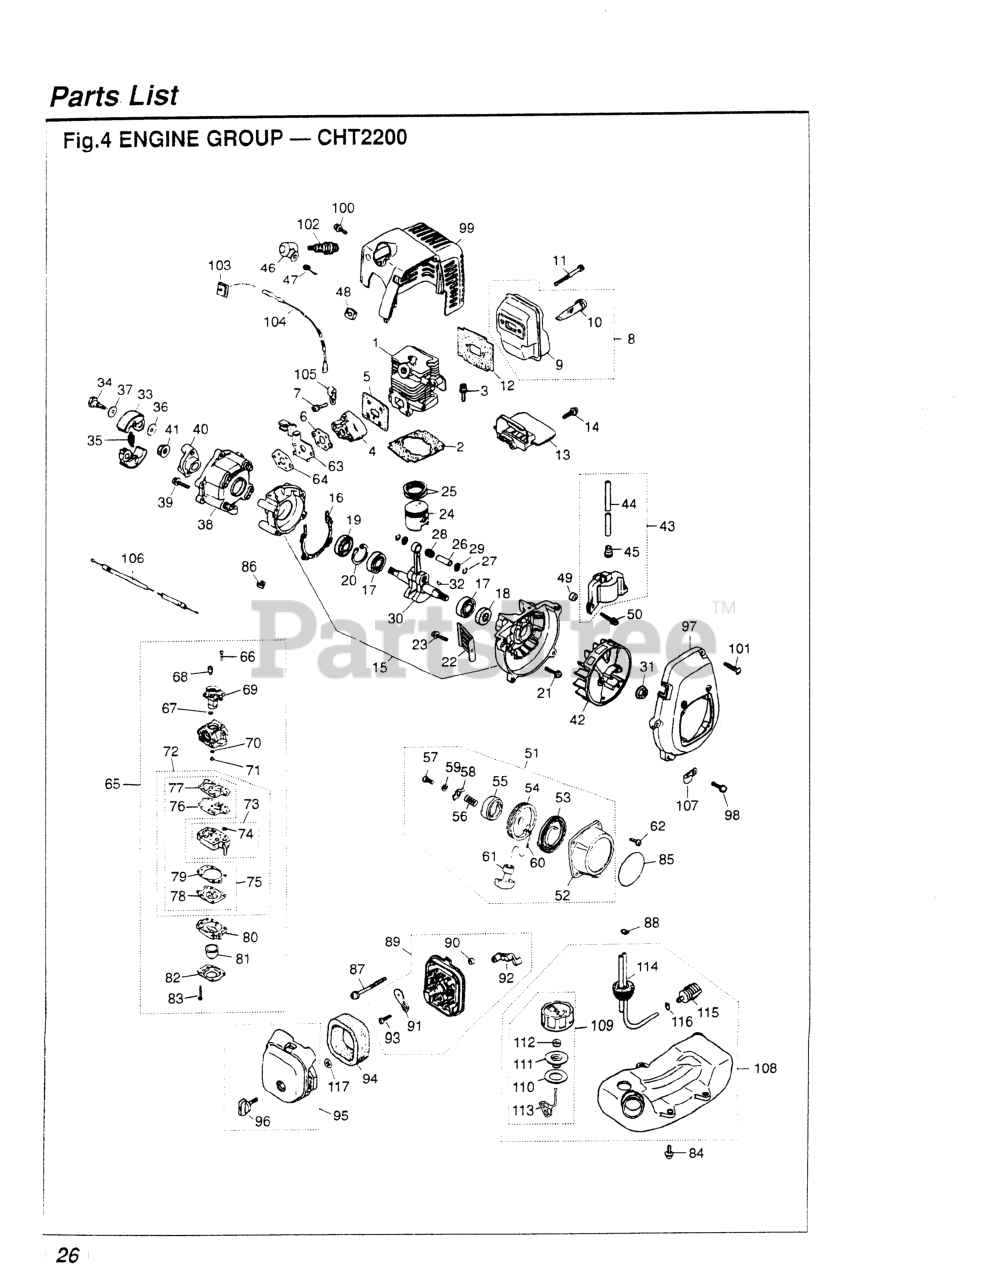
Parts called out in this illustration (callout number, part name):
1	CYLINDER
2	GASKET, BASE (RPLS -12212)
3	BOLT, M5 X 22
4	INSULATOR (REPLACES -13162)
5	GASKET (RPLS -13120)
6	GASKET (REPLACES -13130)
7	SCREW, M5X20 (RPLS.1400-75510)
8	MUFFLER ASSEMBLY
10	ARRESTER (RPLS 5850-15140)
11	BOLT, M5 x 50
12	GASKET, MUFFLER
14	SCREW, M4 X 16
15	CRANKCASE COMP.
16	GASKET (RPLS -21140)
17	BEARING
18	SEAL, OIL (RPLS 1100-21210)
19	SEAL, OIL (RPLS 1140-21220)
20	RING, SNAP, M28 x 1.2
21	BOLT, M5 X 30
23	SCREW,M5 X 14 (RPLS 1400-15510
24	PISTON (REPLACES 1140-41110)
25	RING, PISTON (RPLS 1850-41210)
26	PIN, PISTON 5x8x26
27	RING, SNAP (RPLS 1101-41320)
28	BEARING (RPLS 1140-41330)
29	WASHER
30	CRANKSHAFT (RPLS -42000)
32	KEY
33	SHOE (RPLS 1100-51114)
34	BOLT
35	SPRING
36	WASHER, FLAT (USE 182303)
38	CASE, CLUTCH
39	SCREW
40	PLATE, CLUTCH
43	COIL
45	CAP
46	CAP
47	SPRING
48	GROMMET
49	SPACER (RPLS -71260)
50	BOLT
52	CASE, RECOIL
53	SPRING
54	REEL (USE-75131)
55	5990-75141 (RPLS. 1861-75141)
56	SPRING (REPLACES -75150)
58	RETAINER
59	WASHER
60	ROPE
61	KNOB (REPLACES-75180)
62	SCREW, M4 x 12
63	BRACKET
64	GASKET (REPLACES -13130)
65	CARBURETOR
67	RING
68	SWIVEL
69	VALVE ASSY
70	RING, O
73	BODY, PUMP
74	SCREEN
76	DIAPHRAGM, PUMP
77	GASKET, PUMP
78	DIAPHRAGM
79	GASKET, DIAPHRAGM
80	BODY, PURGE
81	PUMP, PRIMING
82	COVER, PUMP
83	SCREW
84	SCREW
86	CAP, CABLE END
87	SCREW, M5 x 60
88	CLIP
89	BODY-A (RPLS -82101)
90	SLEEVE
91	PLATE, CHOKE (RPLS-82130)
92	LEVER, CHOKE
93	SCREW (REPLACES 50030272)
94	ELEMENT
95	COVER ASSY (RPLS -82202)
96	KNOB (RPLS -82220)
97	COVER, FAN
98	SCREW, M5X20 (RPLS.1400-75510)
99	ENGINE COVER (RPLS-32100)
100	SCREW, M5 x 12
101	SCREW, HOUSING
104	CORD
105	CLAMP
106	CABLE
107	CLAMP
108	5607-85002 (RPLS. 5601-85001)
109	CAP ASSY (RPLS. 5601-85201)
110	PACKING
111	HOLDER - A (RPLS 5601-85230)
112	FILTER
113	STOPPER
114	PIPE COMPLETE
115	FILTER (RPLS 1850-85300)
116	CLIP (REPLACES 2841-31280)
117	CLIP
